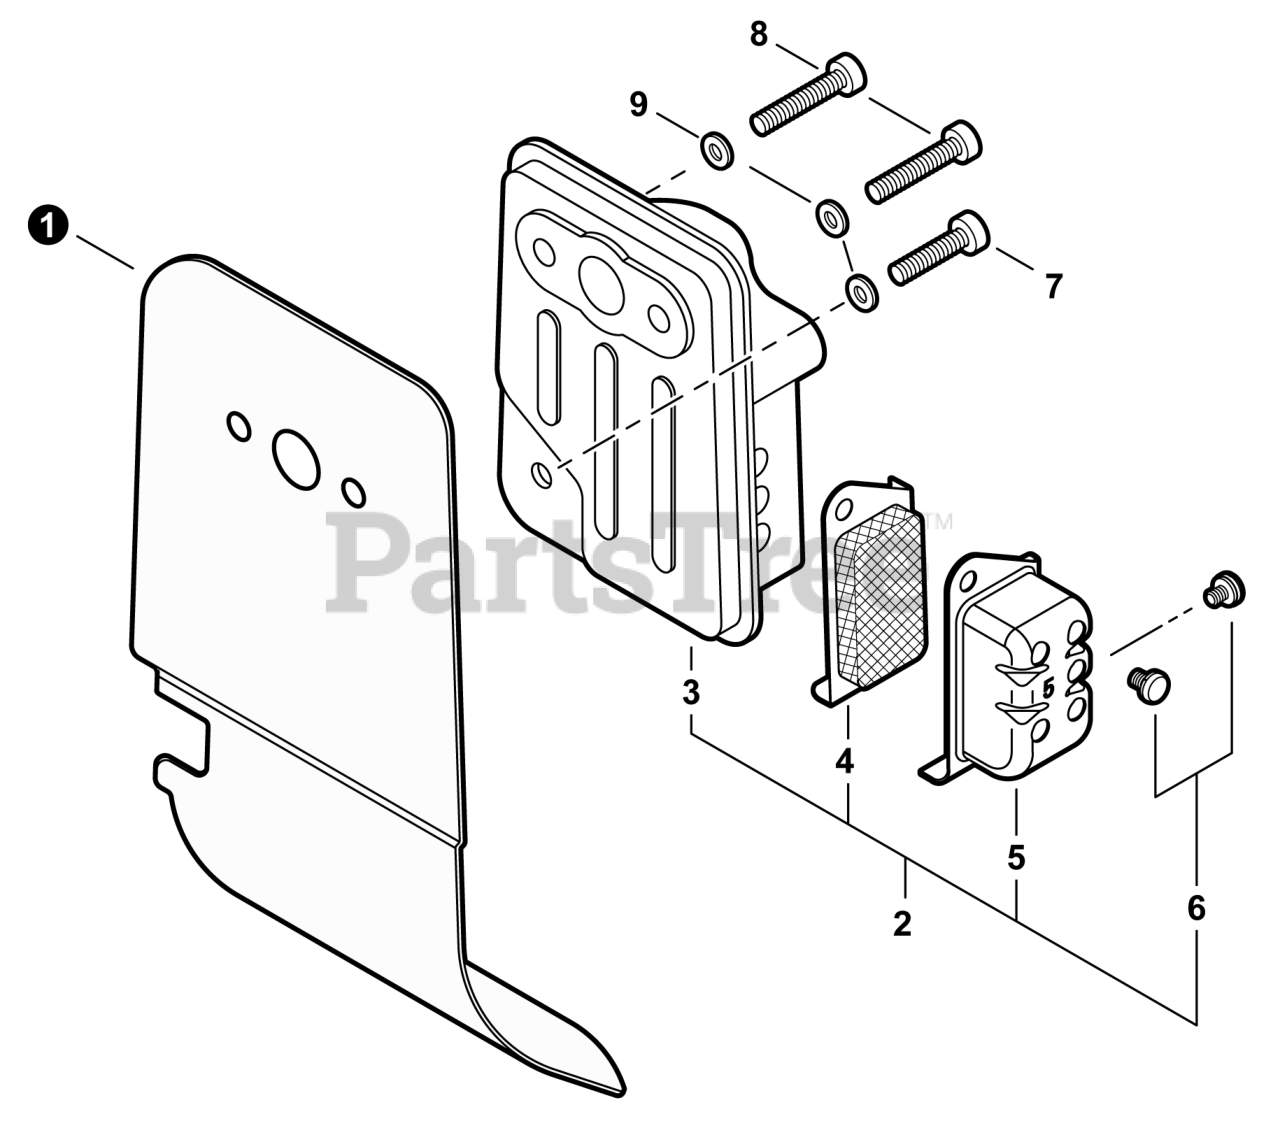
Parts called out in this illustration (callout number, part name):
1	HEAT SHIELD, EXHAUST
2	MUFFLER ASSY
3	MUFFLER
4	SCREEN, SPARK ARRESTER
5	GUIDE, EXHAUST
6	SCREW M4×6
7	BOLT 5×16
8	BOLT M5×25
9	WASHER, FLAT 5.5×10×0.8
